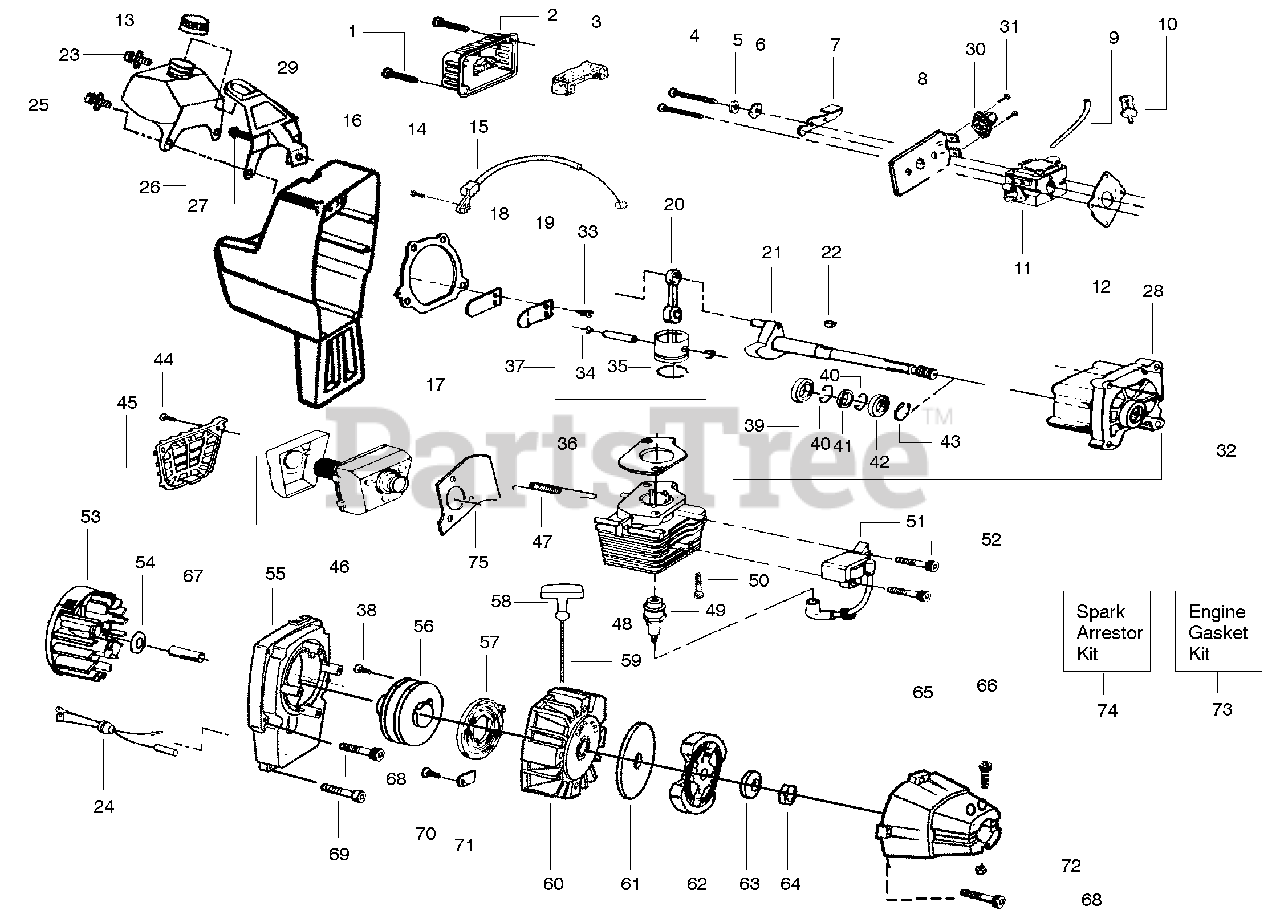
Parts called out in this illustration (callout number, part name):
2	Air Filter Cover
3	Air Filter
5	Choke Spacer
7	Choke Shutter
8	Air Filter Plate
9	Fuel Line Kit
10	Fuel Pick-up Ass'y.
11	Carburetor Ass'y. Kit
12	Gasket-Carburetor
13	Fuel Cap Ass'y.
15	Throttle Cable Ass'y.
17	Gasket-C'case/Shroud
18	Reed Valve
19	Reed Stop
20	Connecting Rod Ass'y.
21	Crankshaft Ass'y.
22	Flywheel Key
24	Leadwire/Grommet Ass'y.
26	Assy-Fuel Tank
27	Screw
28	Crankcase Ass'y.
29	Bracket-Fuel tank
30	Bulb Ass'y.
32	Crankcase/Crankshaft Ass'y.
34	Piston Pin Retainer
35	Piston Ring
36	Gasket-Cylinder
37	Piston Kit
39	Inner Bearing
40	Retaining Ring
41	Crankshaft Seal
42	Outer Bearing
43	Retaining Ring-C'shaft
45	Muffler Guard
46	Muffler Kit
47	Muffler Spring
48	Cylinder Kit
49	Spark Plug (RCJ-8Y)
51	Ignition Module
53	Flywheel Ass'y.
55	Fan Housing
56	Starter Pulley Kit
57	Starter Spring
58	Starter Handle
59	Rope Kit
60	Pulley Housing Ass'y.
61	Washer-Clutch
62	Clutch Ass'y. Kit
63	Washer-Bevel
65	Clutch Housing
67	Spacer-Clutch
71	Retainer
73	Engine Gasket Kit
74	Spark Arrestor Kit
75	Heat Shield/Air Dam
